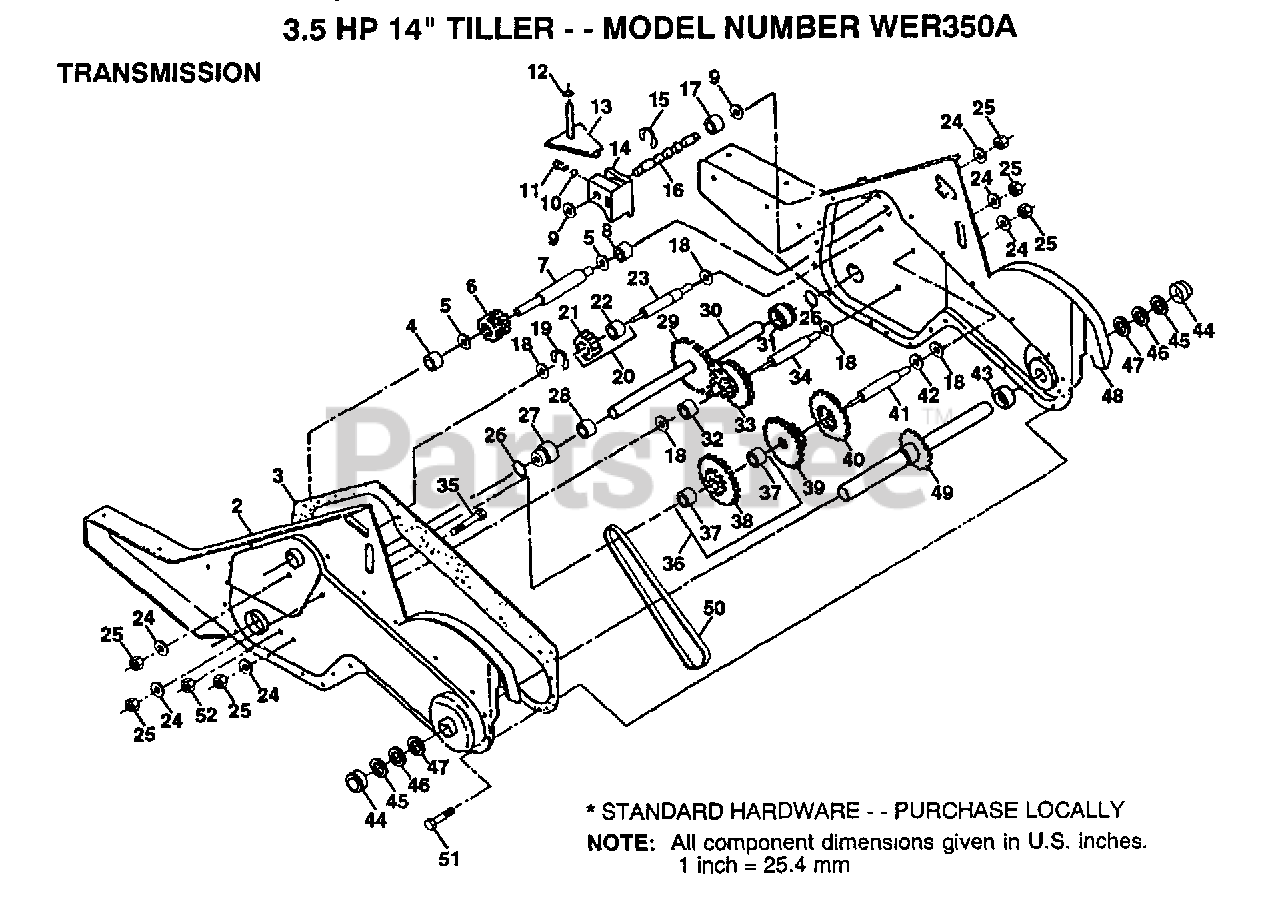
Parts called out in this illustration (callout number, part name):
3	GASKET TI
4	NEEDLE BRNG LT
5	"T, BEARING"
6	PINION-INPUT CRT
7	SHAFT-INPUT CRT
8	"TI, BEARING"
9	WASHER SEAL CRT
11	SPRING-SHIFT CRT
12	SPRING-SHIFT CRT
13	ARM ASSY CRT
14	SHIFT FORK TI
15	KLIP RING
17	SPACER, SPLIT
18	WASHER
19	KLIP RING
20	GEAR ASSY REVERSE IDLER
21	GEAR REVERSE IDLER
22	NEEDLE BEARING TI
24	LOCKWASHER
25	NUT.ASF.HEX.7/16
27	BEARING SHAFT GROUND DRIVE
30	GROUND SHAFT ASSY
31	BEARING SHAFT GROUND DRIVE
33	SPROCKET AND GEAR ASSY
34	SHAFT REDUCTION
35	SCRW WHIZ LOK CRT
36	SPROCKET ASM.
37	BEARING
39	GEAR TI
40	GEAR TI
41	REDUCTION SHFT TI
42	BRNG RACE
43	SPACER TI
44	CUP.FORMED.
45	RING SPIRAL CRT
49	TINE SHAFT
50	CHAIN.50 LINK TI
51	SCREW CRT
52	NUT.HEX.5/16-18
